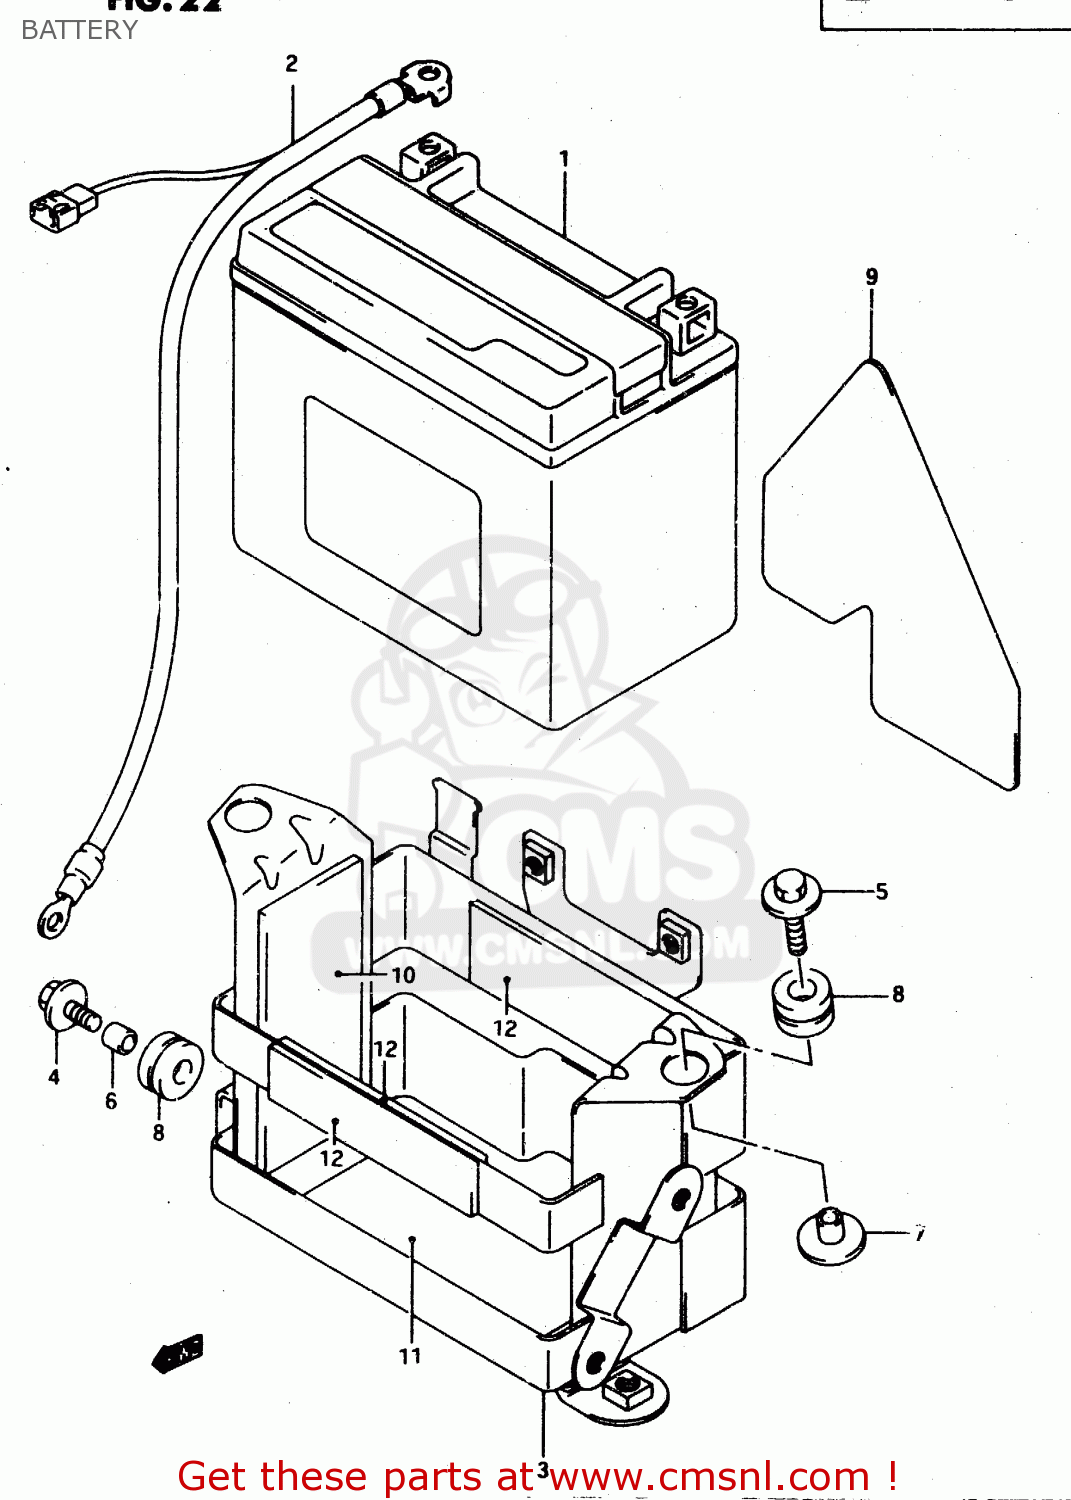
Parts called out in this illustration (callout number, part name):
1	BATTERY ASSY(YTX12-BS,12V10AH)
2	WIRE,BATTERY MINUS LEAD
3	HOLDER,BATTERY
4	BOLT 6X16
5	BOLT(6X25)
6	SPACER(6.1X9X7.5)
7	PLATE,BATTERY HOLDER
8	CUSHION
9	HEAT PROTECTOR,BATTERY
10	PROTECTOR(170X95X3.0)
11	PROTECTOR(170X95X3.0)
12	PROTECTOR(170X95X3.0)
